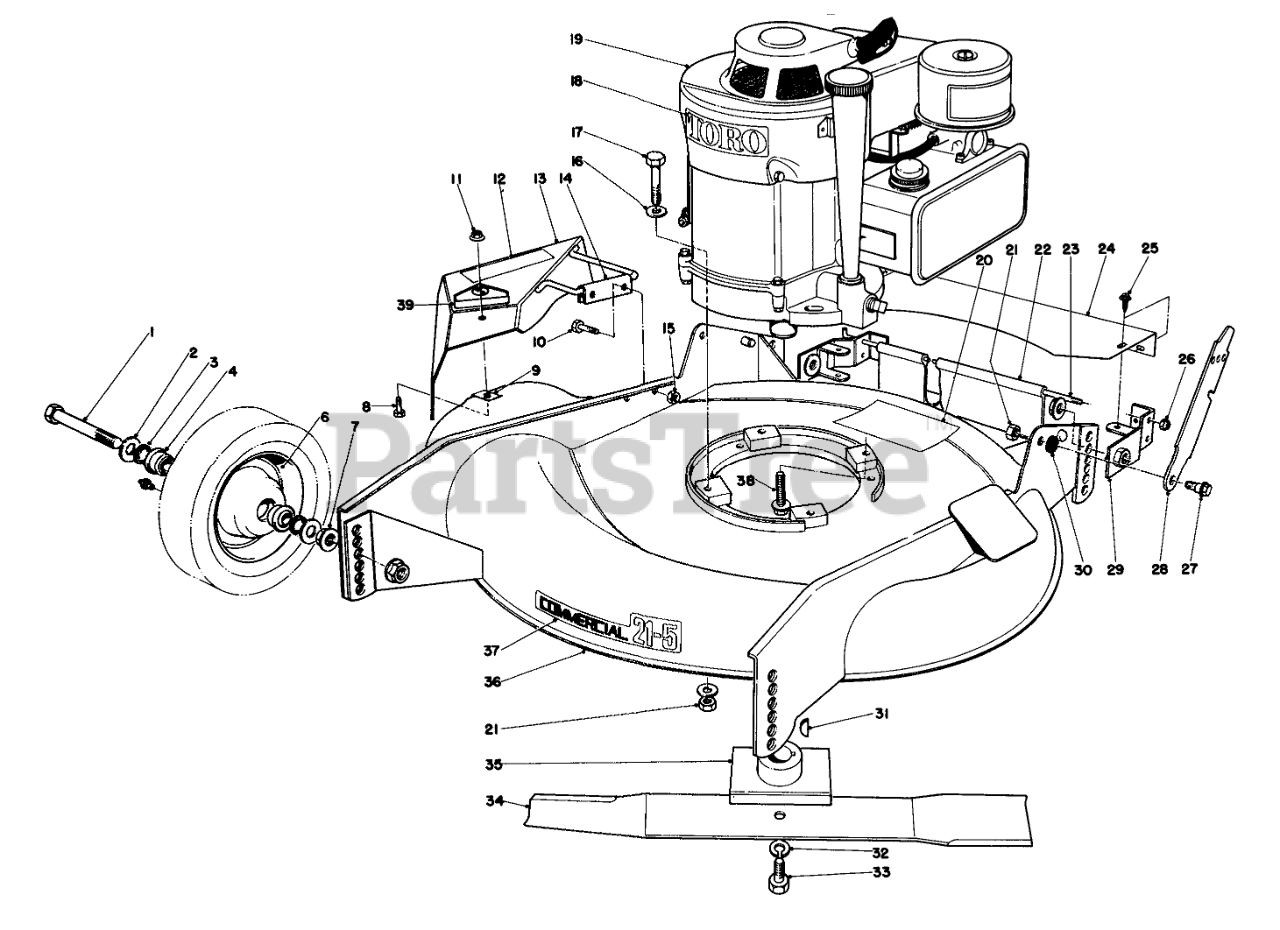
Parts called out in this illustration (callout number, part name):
1	SCREW-HH
2	WASHER-FLAT
3	FELT WASHER
4	BEARING-BALL
6	Wheel & Tire Assy. (Incl. Ref. #4)
7	NUT-HF
8	SCREW-HH
9	NUT-SPEED
10	SCREW-HH
11	NUT-LOCK, HHF
12	Decal
13	Deflector (Incl. Ref. #12 & 39)
14	Hinge-U Bracket
15	NUT-LOCK
16	WASHER-PLAIN
17	SCREW-HH
18	Decal Toro
19	Engine
20	Decal-Saftey Instruction
21	Nut
22	REAR SAFETY SHIELD
23	SHIELD ROD
24	Cover
25	10-16 X 3/8 THDG SCREW
26	NUT-LOCK, NI
27	SCREW-SHOULDER
28	HANDLE LATCH
29	WHEEL AXLE BRACKET WA
30	SPACER
31	KEY-WOODRUFF
32	WASHER-LOCK
33	SPECIAL SCREW
34	BLADE
35	BLADE RETAINER WA
36	Housing (Incl. Ref. #20)
37	Decal-Commercial 21-5
38	SCREW-HWHTF
39	DECAL-DANGER
